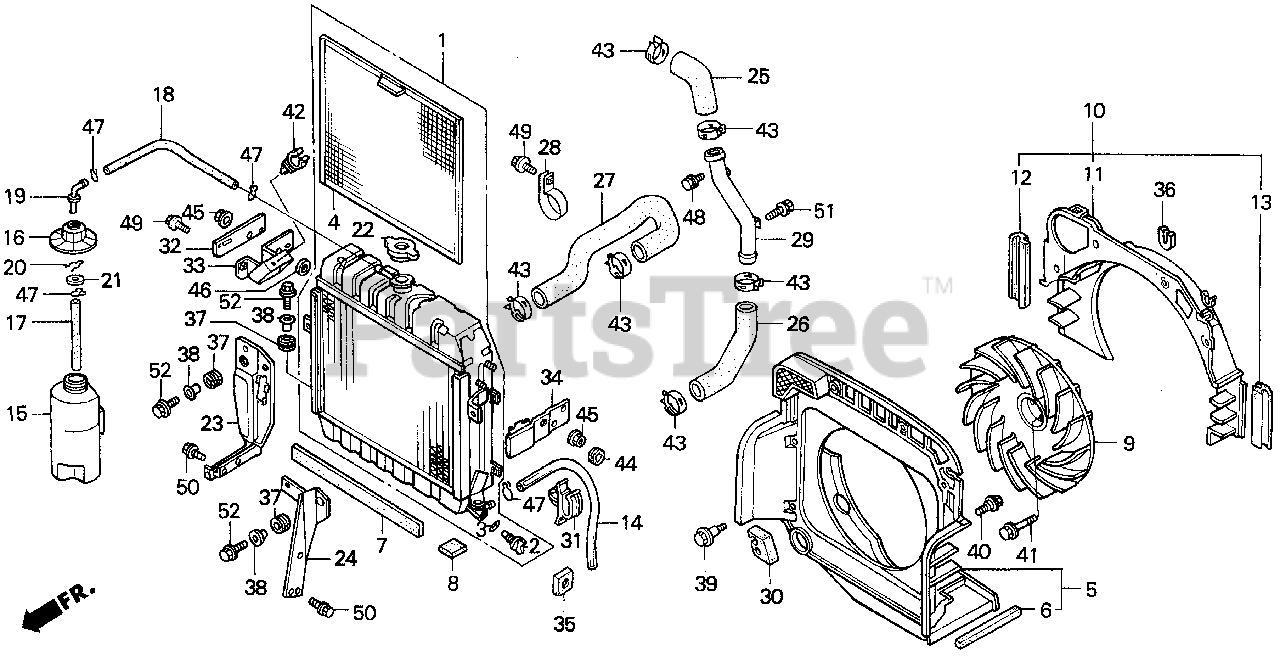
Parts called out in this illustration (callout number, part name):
1	RADIATOR ASSY.
2	VALVE, DRAIN
3	GASKET, DRAIN (TOYO)
4	SCREEN, FR.
5	SHROUD, FR. (P.S.)
6	SEAL, SHROUD
7	SEAL A, RADIATOR
8	SEAL B, RADIATOR
9	FAN, COOLING
10	SHROUD, RR.
11	SHROUD, RR.
12	RUBBER, R. SHROUD SEAL
13	RUBBER, L. SHROUD SEAL
14	HOSE, VINYL (8X11)
15	TANK, RESERVE
16	CAP, RESERVE TANK
17	HOSE, RESERVE TANK
18	TUBE, RESERVE TANK
19	JOINT, RESERVE TANK
20	CLIP, RESERVE TANK JOINT
21	WASHER, RESERVE TANK
22	CAP, RADIATOR FILLER (TOYO)
22	CAP, RADIATOR FILLER
23	BRACKET, R. RADIATOR
24	BRACKET, L. RADIATOR
25	HOSE A, WATER (UPPER)
26	HOSE B, WATER (UPPER)
27	HOSE, WATER (LOWER)
28	BAND, WATER HOSE
29	PIPE, CONNECTING
30	HOLDER, WIRE HARNESS
31	CLIP B, HARNESS
32	BRACKET A, MAIN FUSE
33	BRACKET B, MAIN FUSE
34	BRACKET, POWER STEERING TANK
35	RUBBER, RADIATOR DRAIN SEAL
36	PLATE, HEADLIGHT STAY SETTING
37	RUBBER, HEADLIGHT SETTING
38	COLLAR, SEAT SETTING
39	BOLT, TANK SETTING
40	BOLT, SPECIAL (6MM)
41	BOLT, FLANGE (7X35)
42	HOLDER, HOOD OPEN ROD
43	CLAMP, TUBE (D29)
44	GROMMET, HOOD STAY
45	NUT, FLANGE (6MM)
46	WASHER, PLAIN (6MM)
47	CLIP, TUBE (C11)
48	BOLT, FLANGE (6X10)
49	BOLT, FLANGE (6X12)
50	BOLT, FLANGE (6X14)
51	BOLT, FLANGE (6X22)
52	BOLT, FLANGE (8X22)
